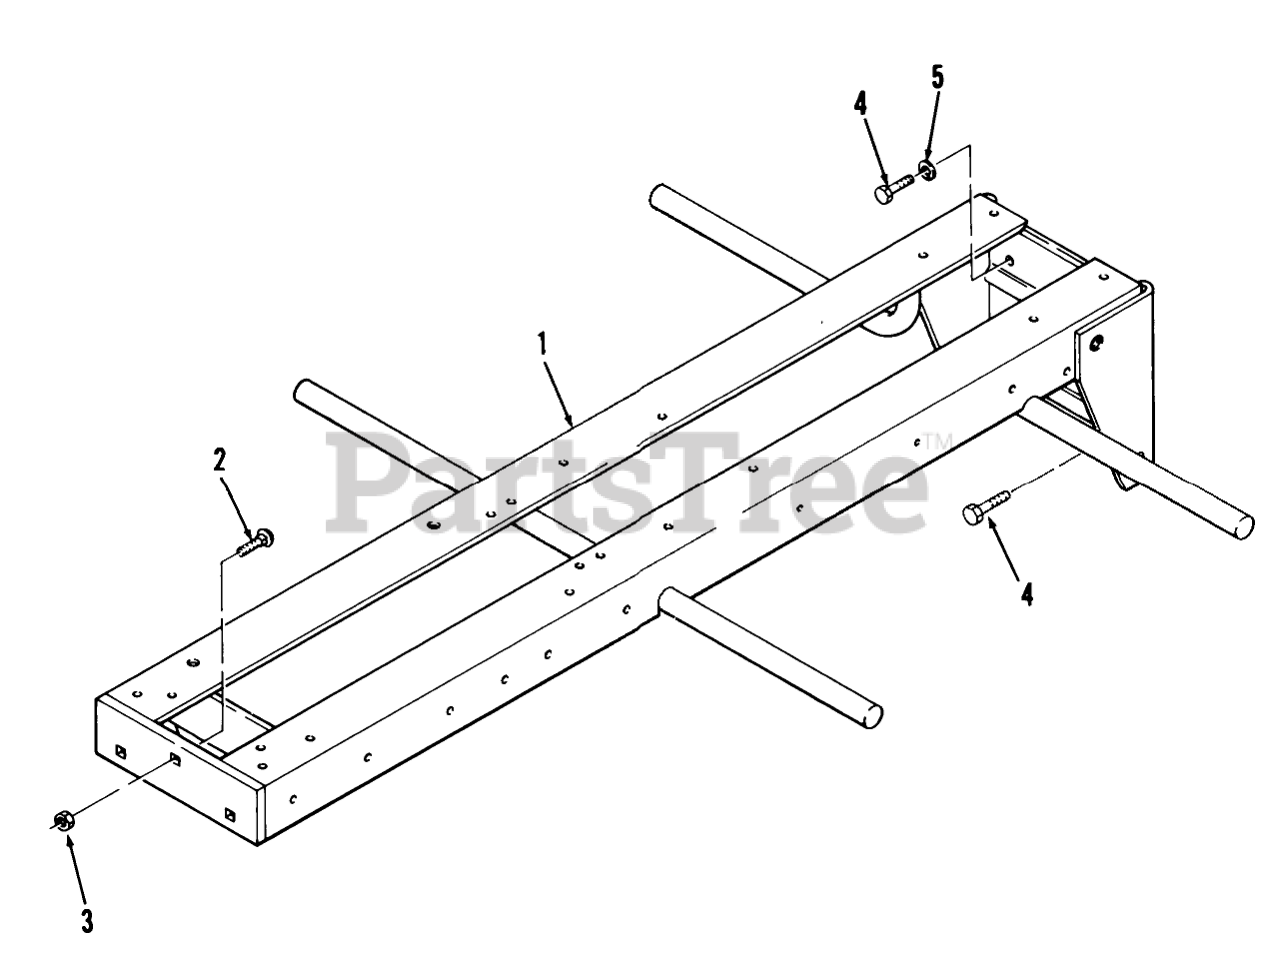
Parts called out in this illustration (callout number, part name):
1	Frame
1	Frame 520-HC
2	Bolt
3	NUT
4	Bolt
5	LOCKWASHER
